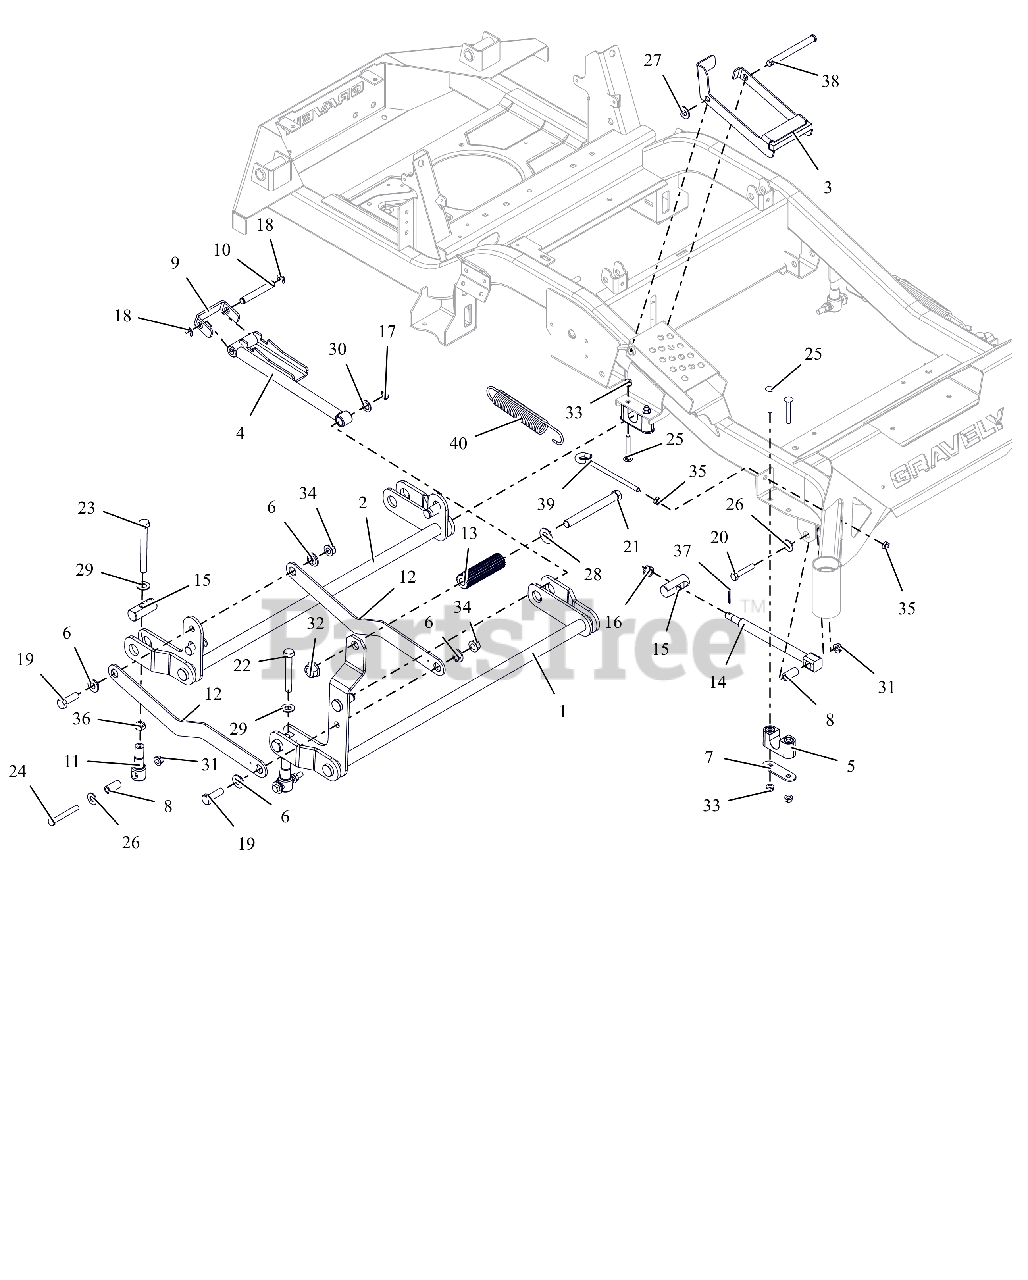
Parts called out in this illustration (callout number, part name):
1	WLDMT, FRONT DECK LIFT PIVOT
2	WLDMT, REAR DECK LIFT PIVOT
3	BRKT, HOC TRANSFER LOCK
4	WLDMT, HOC ARM
5	ASM-BUSHING, DECK LIFT
6	BSHG-FLG .515X.750X.310X1.120
7	PLATE, BEARING SUPPORT
8	SPACER, DECK LEVELING
9	BRKT, HOC LINE
10	ROD, HOC PIVOT
11	LINK, DECK LIFT FORMED
12	LINK, DECK LIFT
13	ROD, FOOT PEDAL (BLACK)
14	DRAG,LINK-HD
15	PIN, DECK LIFT
16	NUT-SL .50-13
17	RG-RTNG-EXT .625X.050
18	RG-RTNG-EXT .500X.042 (E)
19	BLT,HEX .50-13X1.50 G5 ZCC
20	BLT,HEX .38-16X2.00 G5 ZCC
21	BLT, HEX .62-11X5.50 G5 FBP
22	BLT, HEX 0.5-13X3.5F GR5 ZCC
23	BLT, HEX .50-13X4.50F G8 ZCC
24	BLT, HEX .38-16X2.75 G8 ZCC
25	BLT, RHSSN.31-18X2.25 G5 ZCC
26	WSHR,FLT .438X1.00X.083 ZCC
27	WSHR,FLT .531X1.062X.095 ZCC
28	WSHRFLT 5/8SAE CARBHARD FBP
29	WSHR, FLT .557X1.040X.102 ZCC
30	WSHR, FLT .630X1.005X.062 ZCC
31	NUT-LK-TOP-FLG .38-16 ZC120
32	NUT,FLG-TOP LK .625-11 FBP
33	NUT,LK-CTR-FLG .31-18 GF ZCC
34	NUT-LK-TOP-FLG .500-13 GF ZCC
35	NUT-JAM .375-16 G2 ZCC
36	NUT-JAM .500-13 G2 ZCC
37	PIN,CTR.12X1.25EXTPRSQCT ZC120
38	PIN, SLIC-.500X4.97X4.55 -ZC
39	BOLT,.38-16 X 5.25-.62 DIA EYE
40	SG-TENS .162X1.25X8.25 WLD 25
